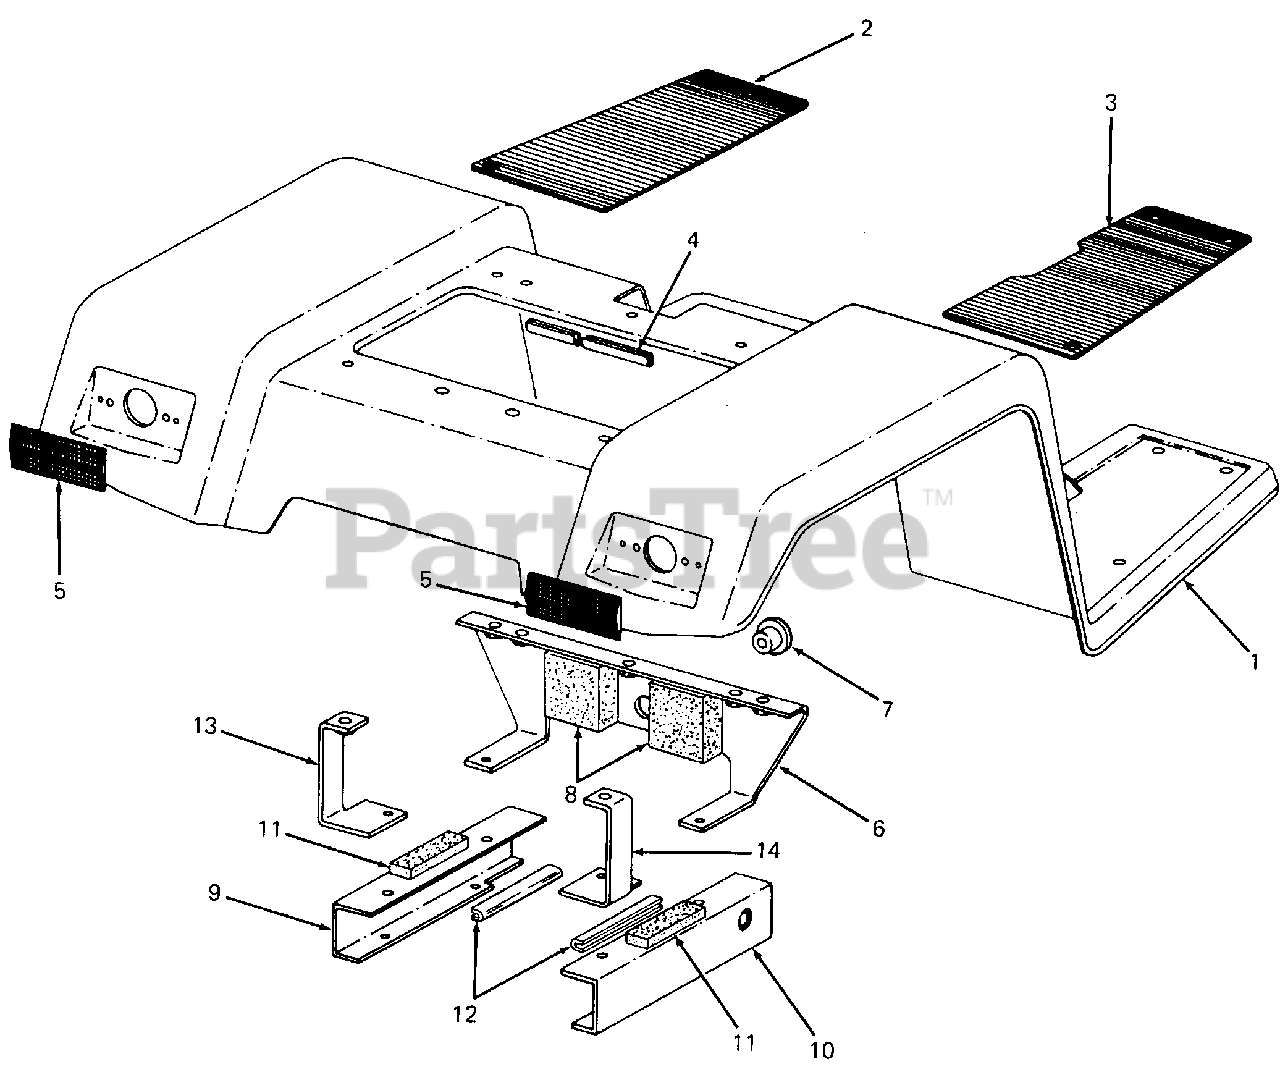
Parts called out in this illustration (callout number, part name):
2	Pad, Foot Rest, LH
3	Pad, Foot Rest, RH
4	Strip, Trim, 39.38 in. Lg
5	Reflector
6	Support, Front Fender
7	Bushing, Snap, 7/8 ID
8	Strip, Foam Gasket Sealing, 3 in. Lg
9	Support, Fender, LH
10	Support, Fender, RH
11	Strip, Foam Gasket Sealing, 5 in. Lg
12	Strip, Trim, 4 in. Lg
13	Support, Rear Fender, LH
14	Support, Rear Fender, RH
